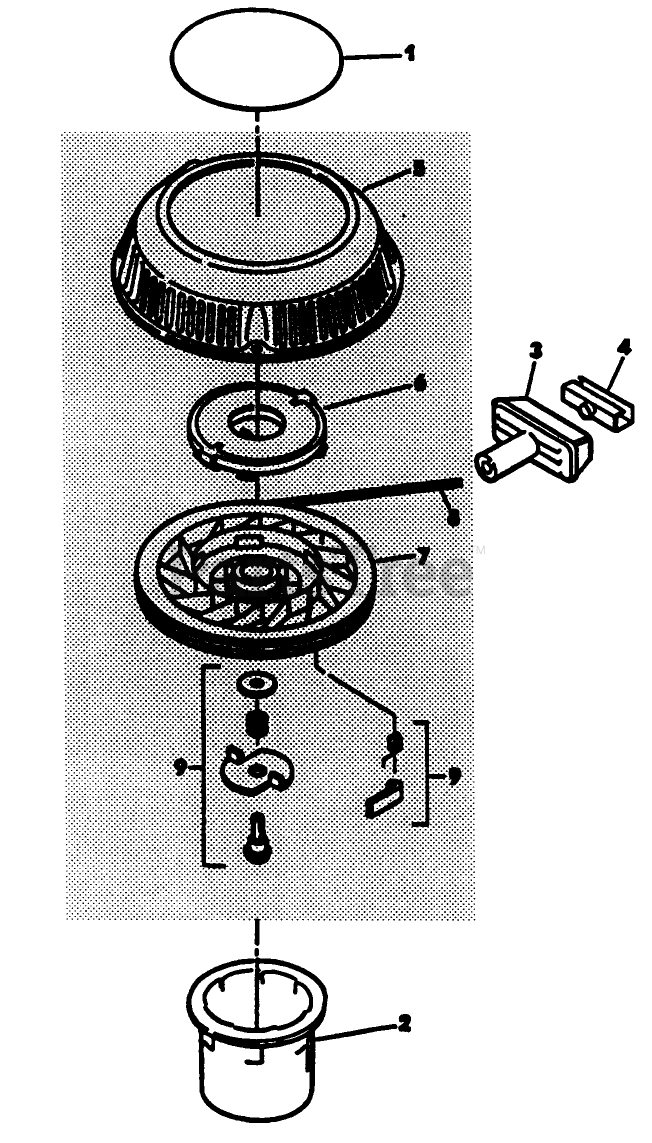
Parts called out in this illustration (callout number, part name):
2	HUB-STARTER E COMM.
4	CLIP-STARTER
5	STARTER HOUSING & SHAFT
7	PULLEY
9	DOG KIT
